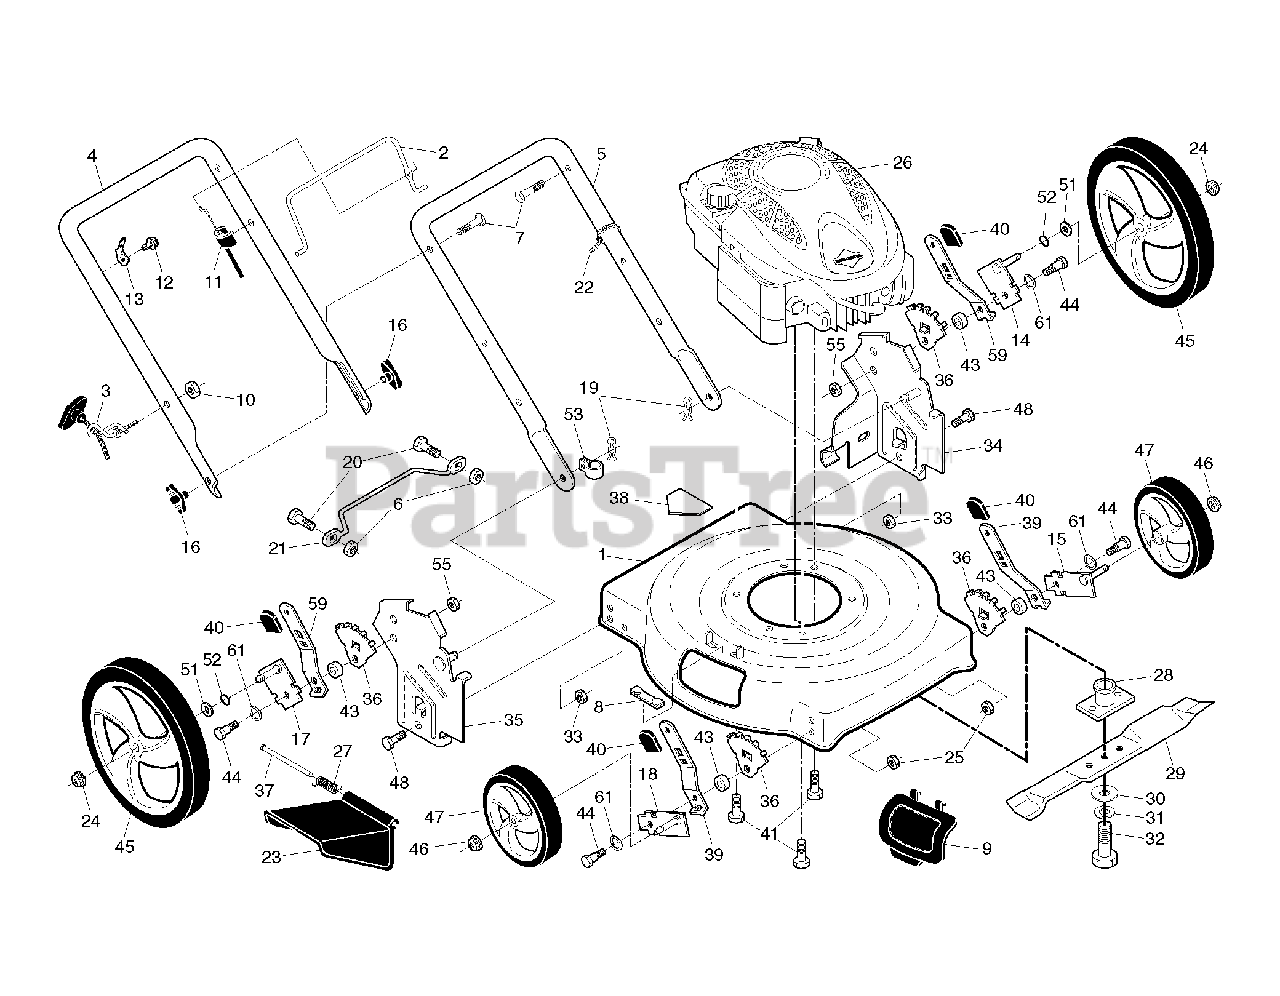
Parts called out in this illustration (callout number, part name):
3	GUIDE.ROPE.STD.BLK.ZIN
4	HANDLE.UPPER
5	HANDLE.LOWER.BLACK
7	BOLT, HANDLE 5/16-18X1.75
10	NUT
13	BRACKET.UPSTOP.RT
14	AXLE ARM ASSY REAR LH
15	AXLE ARM ASSY FRONT LH
16	KNOB, DEFLECTOR
17	AXLE ARM ASSY REAR RH
18	AXLE ARM ASSY FRONT RH
19	HAIRPIN COTTER
22	TIE GUIDE
24	NUT.HEX.FLANGE.3/8-16.LOCKNUT
25	NUT.FLANGE.HEX.5/16X18.BLACK
27	SPRING.HINGE
28	RP BLADE ADAPTER
30	WASHER,HARDEN
31	LOCKWASHER
32	SCREW, HEX HD 3/8-24 X 1-3/8
33	NUT.71038.31-18.HEX.NYLOCK
34	BRKT.ASM.HDL.22.ECON.
35	BRKT.ASM.HDL.
36	WHEEL ADJ BRACKET FRONT
38	DECAL.INTERNATIONL.CUTFINGER
39	SELECTOR SPRING, FRONT
40	SELECTOR KNOB
41	BOLT 3/8-16X1-1/8
43	SPACER.HEIGHT.ADJUSTER
44	SHOULDER BOLT 5/16-18
46	NUT.HEX.FLANGE.3/8-16.LOCKNUT
51	WASHER PM
52	O-RING..070X.487.NEOPRENE
53	CLIP.CABLE.BLK
55	NUT, LOCK 5/16-18
59	SPRING.SEL.EXT.21.DOMED.12/14
61	WASHER FLAT
